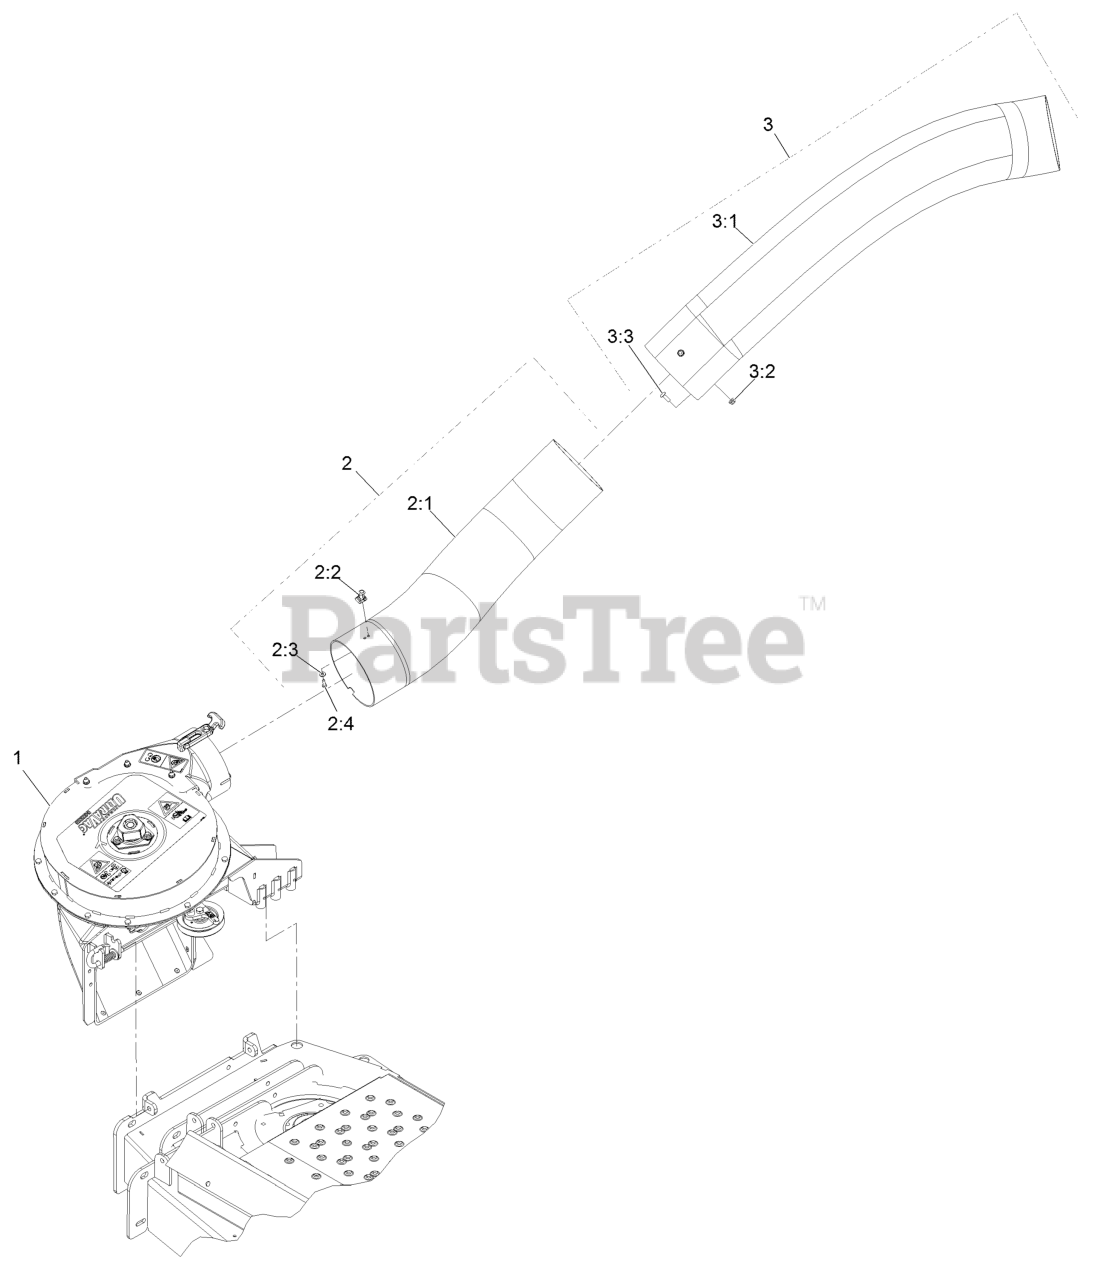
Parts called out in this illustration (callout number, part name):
1	ASM-BLOWER UV E SERVICE
2	LOWER TUBE ASM
2:1	TUBE-LOWER
2:2	LATCH-KEEPER
2:3	WASHER-FLAT
2:4	SCREW-PPH
3	UPPER TUBE ASM
3:1	TUBE-UPPER
